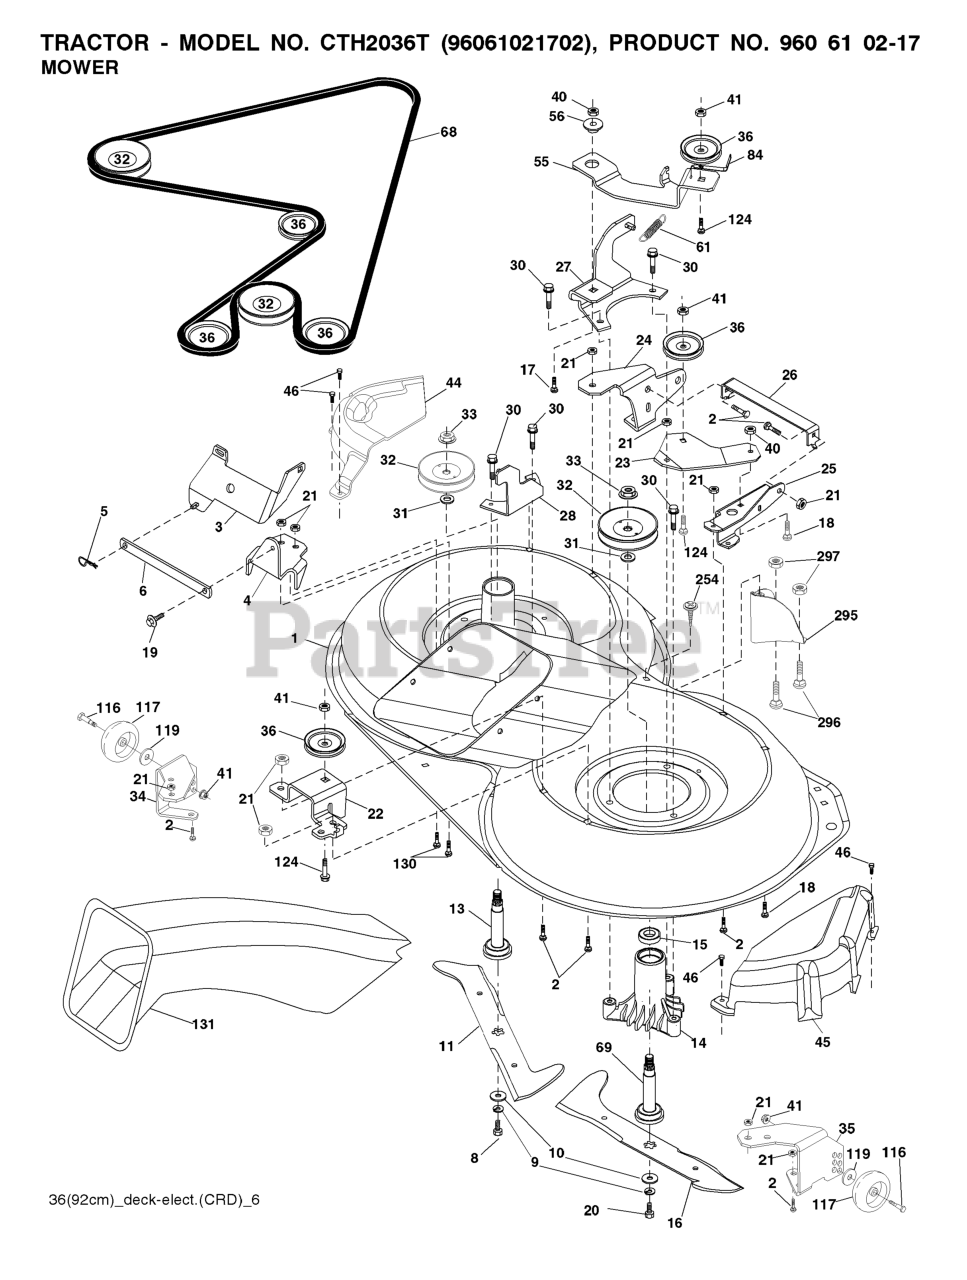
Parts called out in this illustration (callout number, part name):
2	RP BOLT 5/16-18 X3/4 ZN/YEL GR
5	RETAINER-SPRNG RB
6	BAR.SWAY.92.CRD
8	BOLT.3/8-24X1.25 GR8
9	LOCKWASHER
10	WASHER.BLADE
13	SHAFT ASM VENT
14	HOUSING.MANDREL.VENTED (MACHD)
17	BOLT.3/8-14X1.25
19	BOLT SHD 5/16-18
20	BOLT.3/8-24X1.25GR8. LHTHRD
21	LOCKNUT
26	SUPPORT
30	SCREW, WASHER HEAD
31	WASHER.SPACER.MANDREL
32	PULLEY MANDREL
33	NUT.FLANGE.LOCK.TOP
36	PULLEY.IDLER.4.25
41	NUT LOCK FLG 3/8-16 UNC
45	COVER.MANDREL.RH.CRD
46	SCREW.1/4-20X5/8
55	ARM.IDLER.92 CRD.2006
56	SPACER.RETAINER.MOWER
61	SPRING
68	BELT.DRIVE.92CM.CRD.2006
69	SHAFT.ASM.W/LWR.BRG.RH.THREAD
84	KEEPER, BELT IDLER
116	BOLT.SHOULDER.3/8-16X3-5/8.
117	RP WHEEL. GUAGE RALLY
119	WASHER
124	BOLT.3/8-16X1.50
130	BOLT.CARR.SQNK.5/16-18UNC.X3/4
131	CHUTE BAGGER
254	SCREW 3/8-16X1
296	BOLT
297	NUT CENTERLOCK
